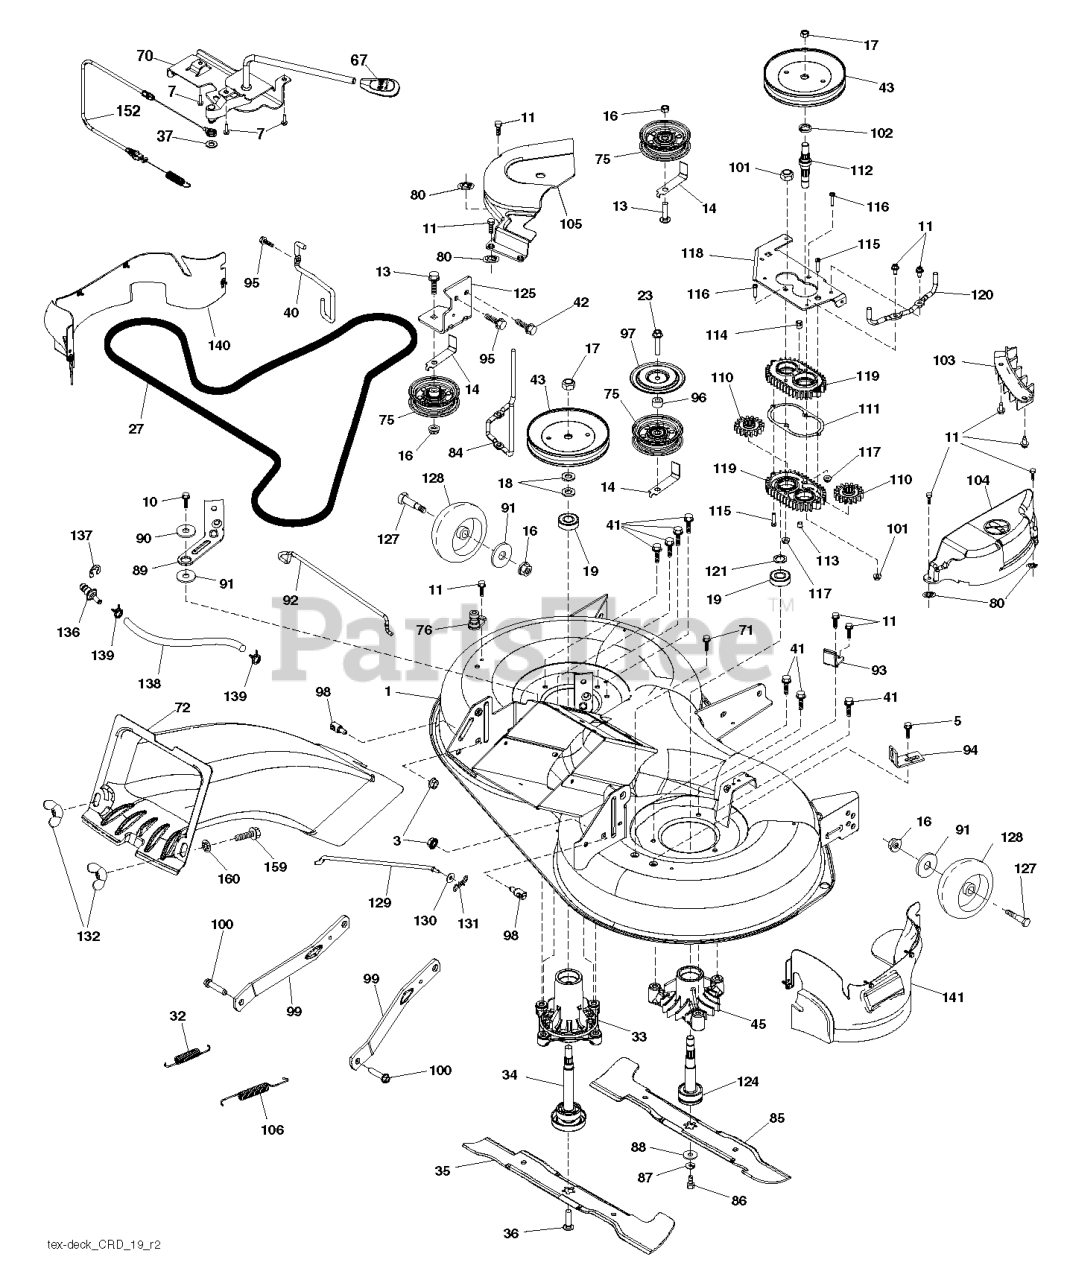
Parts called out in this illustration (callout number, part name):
1	DECK.WELDMENT.97.TEX.498
3	NUT LOCK HEX FLANGE 5/16-18
5	BOLT.5/16HEX.WHS.HD
7	SCREW.#10 X 0.750.BOS
10	SCREW 3/8-16X1
11	SCREW.1/4-20X5/8
13	BOLT.3/8-16X1.50
14	KEEPER, BELT IDLER
16	NUT LOCK FLG 3/8-16 UNC
17	NUT.FLANGE.LOCK.TOP
18	WASHER.SPACER.MANDREL
23	SCREW LT
27	BELT V-BELT DRIVE
32	SPRING RETURN
33	RP.HOUSING.MANDREL.4PT.
34	SHAFT.ASM.MDRL.N/GREASE.38
35	BLADE.3N1.LH.CRD.97
36	BOLT.WASHER.ASM.7/16-2
37	WASHER
40	KEEPER BELT ENGINE LH
41	BOLT.HEX.WASHR.HED.313-18X1.19
42	SCREW
43	PULLEY.MANDREL.5.438.PD
45	HOUSING.MANDREL.44/46" VENT
67	HANDLE.CLUTCH.CABLE.LT
70	CLUTCH.ASM.MANUAL.LT.PRED
71	SCREW 3/8-16X1/2
72	CHUTE REAR CRD UPPER CHUTE TEX
75	FLAT IDLER PULLEY
76	1/2" BARB.DECK.WASHOUT.PORT
80	PALNUT 1/4
84	KEEPER.BELT.MANDREL.PULLEY
85	BLADE.3N1.RH.CRD.97
86	BOLT.3/8-24X1.25GR8. LHTHRD
87	LOCKWASHER
88	WASHER.BLADE
89	ARM.BRAKE.97.LH
90	SPACER.RETAINER
91	WASHER
92	ROD ROD BRAKE
93	ARM.BRAKE.97.RH
94	BRKT.CLUTCH.CABLE
95	SCREW, 3/8-16X3/4
96	SPACER
97	PROTECTOR
98	STUD.FASTNER.W/ANTI-ROTATE
99	ARM.SUSPENSION.MOWER.R
100	BOLT.SHOULDER
101	NUT.CROWNLOCK.9/16 -18.UNC
102	SPACER BEARING
103	GUARD GUARD FRONT VENT
104	97.CRD.RH.MANDREL.COVER
105	MANDREL MANDREL COVER LH
106	SPRING.BRAKE.RETURN.38"
110	CRD.SPUR.GEAR
111	GASKET GASKET GEARCASE
112	SHAFT SHAFT. CRD GEARCASE ADAP
113	PLUG PLUG OIL
114	VALVE VALVE RELIEF
115	SCREW
116	BOLT.CARIGE.SS.1/4-20X1.75GR5
117	NUT T
118	ARM ARM CLUTCHING
119	GEARCASE GEARCASE SUBASM
120	BRACKET KEEPER BELT RH
121	WASHER WASHER
124	MANDREL SHAFT NON/GREASE
125	BRACKET
127	BOLT.SHOULDER.3/8-16X3-5/8.
128	RP WHEEL. GUAGE RALLY
129	ROD.ANTI.SWAY.48/54"K4
130	WASHER
131	PIN.COTTER.5/16.BOW TI
132	KNOB.HANDLE.3/8.TRI-POINT.BLAC
136	PLUG WASHOUT PORT HOOKUP
138	HOSE.3/8ID.BULK.12"
139	HOSE.3/8.CLAMP (2 2)
140	GUARD
141	GUARD SUBASM.TEX CRD 97CM RH F
152	CABLE CABLE CLUTCH MANUAL W/S
159	BOLT
